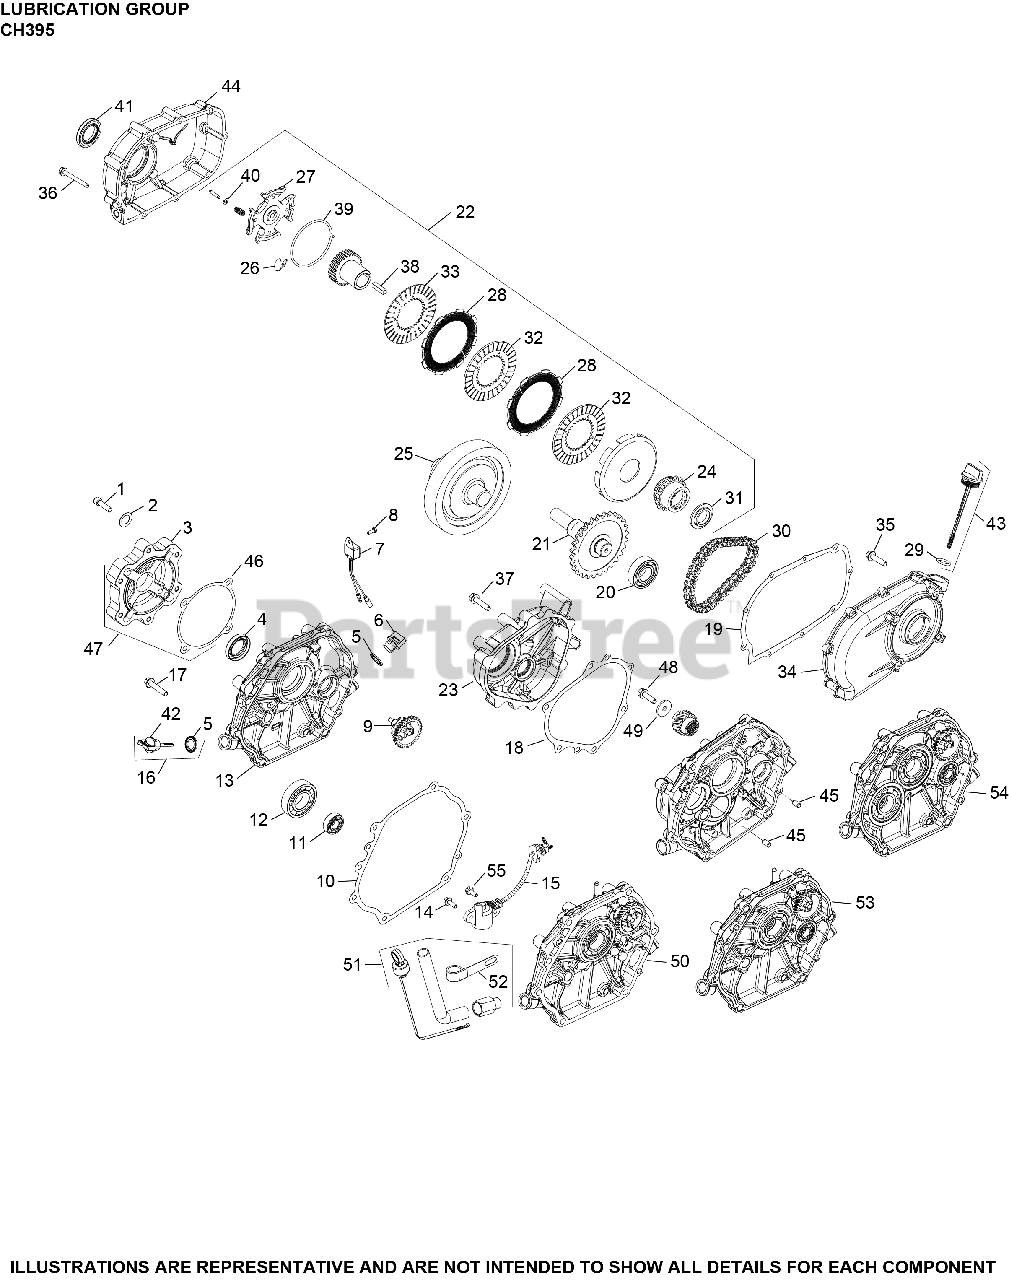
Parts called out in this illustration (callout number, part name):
5	SEAL, OIL
7	CONTROL, OIL ALERT UNIT
8	SCREW, HEX/PHILLIPS M5
9	GOVERNOR, ASSEMBLY
12	BEARING, CRANKSHAFT
15	SWITCH, OIL SENSOR ASSEMBLY
16	DIPSTICK ASSEMBLY
17	SCREW, CLOSURE PLATE (CKY)
42	DIPSTICK - USE 17 038 08-S
50	PLATE, CLOSURE & BEARING
55	SCREW, M6 X 16
